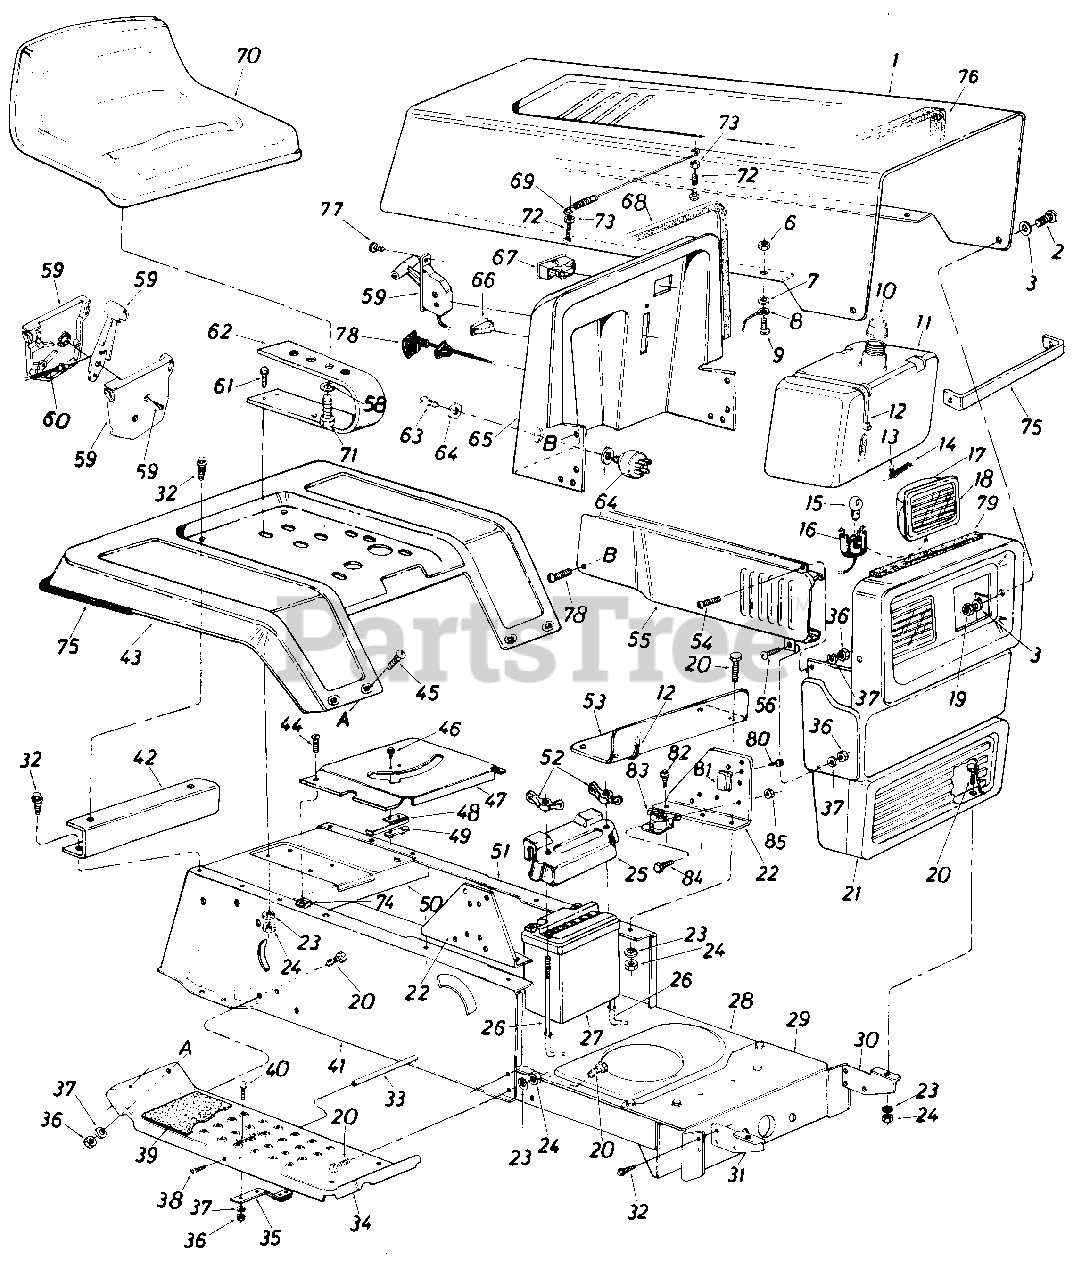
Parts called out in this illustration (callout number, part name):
1	Hood
2	Truss Hd. Scr. 1/4-20 x .75" Lg.
3	Fl-Wash. .296" I.D. x .62" O.D.
6	Hex Sems Nut #10-24 Thd.
7	Fl-Wash. .203" I.D. x .41 O.D. x .040
8	Hood Stop
9	Truss Hd. Scr. #10-24 x 1/2" Lg.
10	Fuel Cap Gauge
11	Fuel Tank
12	Tie Strap
13	Hose Clamp
14	Fuel Line
15	Lamp
16	Socket
17	Headlight Housing
18	Lens
19	Hex Sems Ins. L-Nut 1/4-20 Thd.
20	Hex Bolt 5/16-18 x .75" Lg.
21	Grille
22	Dash Support Bracket
23	L-Wash. 5/16" I.D.
24	Hex Nut 5/16-18 Thd.
25	Battery Cover
26	Battery Hold Down Rod
27	12V Battery
28	Lower Frame
29	Front Pivot Brk't.
30	Grille Mount Brk't. L.H.
33	Running Board Rod
34	Running Board
35	Blade Brake Ass'y.
36	Hex Nut 1/4-20 Thd.
37	L-Wash. 1/4 I.D.
38	Truss Mach. Scr. 5/16-18 x .75" Lg.
39	Foot Pad
40	Carriage Bolt 1/4-20 x .62"
41	R.H Side Frame
42	Fender Mount Brace
43	Rear Fender
44	Truss Mach. Tap Screw #10 x .50"
45	Carriage Bolt 1/4-20 x .50"
46	Truss Hd. Scr. #10-24 x .50 Lg.
47	Transmission Panel
48	Reverse Safety Switch
49	Insulator Nut Plate
50	Hitch Plate
51	L.H. Side Frame
52	Wing Nut 1/4-20 Plastic
53	Fuel Tank Support
54	Truss Hd. Scr. 1/4-20 x .75 Lg.
55	Side Cover R.H.
56	Truss Mach. Scr. 1/4-20 x .50 Lg.
58	L-Wash. 1/2" I.D.
59	Throttle Control Box Ass'y.
60	Throttle Control Wire
61	Hex Bolt 5/16-18 x 1.00" Lg.
62	Seat Spring 5.5 High
63	Ignition Key
64	Ignition Switch
65	Dash Panel
66	Light Switch
67	Ammeter
68	Molding Strip
69	Hood Spring
70	Seat Ass'y.
71	Hex Bolt 1/2-13 x 1.0" Lg.
72	Hex Bolt #10-24 x 1.0" Lg.
73	Hex Top L-Nut #10-24
74	Speed Nut #10Z
75	Tie Strap Grille Side Panel
76	PVC-Foam
77	Truss Mach. Scr. AB-Tap #10 x .50 Lg.
78	Choke Control Comp.
79	Foam Strip 3/8 x 1 x 14 Lg.
80	Hex Wash. Hd. AB-Tap Scr. 1/4 x.50 Lg.
81	Circuit Breaker
82	Hex Thd. Rolling Scr. 5/16-24 x .75 Lg.
83	Solenoid
84	Hex Bolt 1/4-20 x .50 Lg.
85	Hex Sems Nut 1/4-20 Thd.
